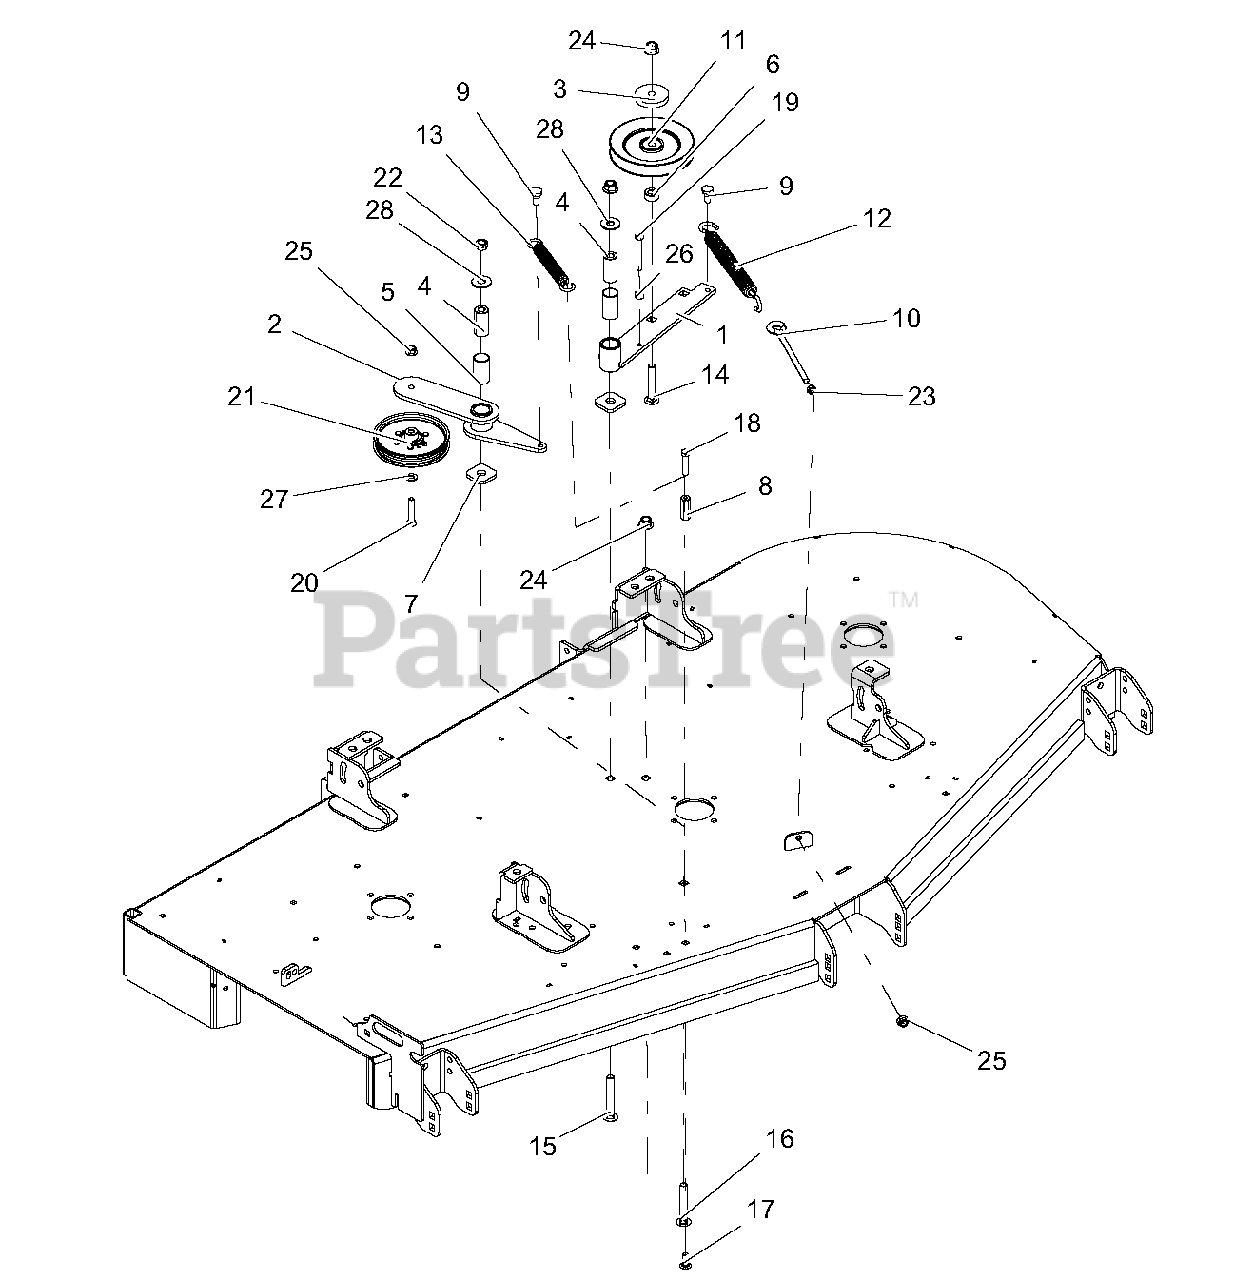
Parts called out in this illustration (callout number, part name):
1	PTO IDLER ARM W/BUSHING
2	DECK RH DRIVE IDLER ARM W/BUSHING
3	CAP, IDLER BEARING SEALING
4	BSHG, SPCR .502X.997X2.03
5	BSHG, 1.00X1.125X1.937
6	BSHG, SPCR .502 X .997.50 PM
7	WSHR, -FLT.640X1.75X.250
8	NUT-HEX COUPLING
9	BLT, SHLDR EP .38-16X.30 HEX YZ
10	BOLT, .38-16X6.00 .62 DIA EYE
11	SHEAVE, .50" ID X 6.00" OD V-IDLER
12	SPRG, EXTENSION
13	SPRG, EXTENSION
14	@BLT-RDHDSQNK .50-13X3.00 G5 Y
15	@BLT-RDHDSQNK .50-13X3.50 G5 Y
16	@BLT-RDHDSQNK .50-13X3.25 G5 Y
17	@BLT-RDHDSHSQNK.38-16X1.0 G5YZ
18	BLT-HEX .38-16X1.75 GR5 YWZC
19	BLT-HEX .38-16X2.75 GR5 YWZC
20	BLT-HEX .38-16X2.00 GR5 YWZC
21	PULLEY, FLAT 5.00X.375 W/BRG
22	@NUT-LK-CTR .50-13 YWZC
23	NUT, JAM .375-16 YWZC
24	NUT-LK-NYL-FLG .50-13 YWZC
25	NUT-LK-NYL-FLG .38-16 YWZC
26	NUT-HEX .38-16 YWZC
27	@WSHR-FL-STL.406X.812X.065 YWZ
28	@WSHR-FL-STL.563X1.38X.109YWZC
